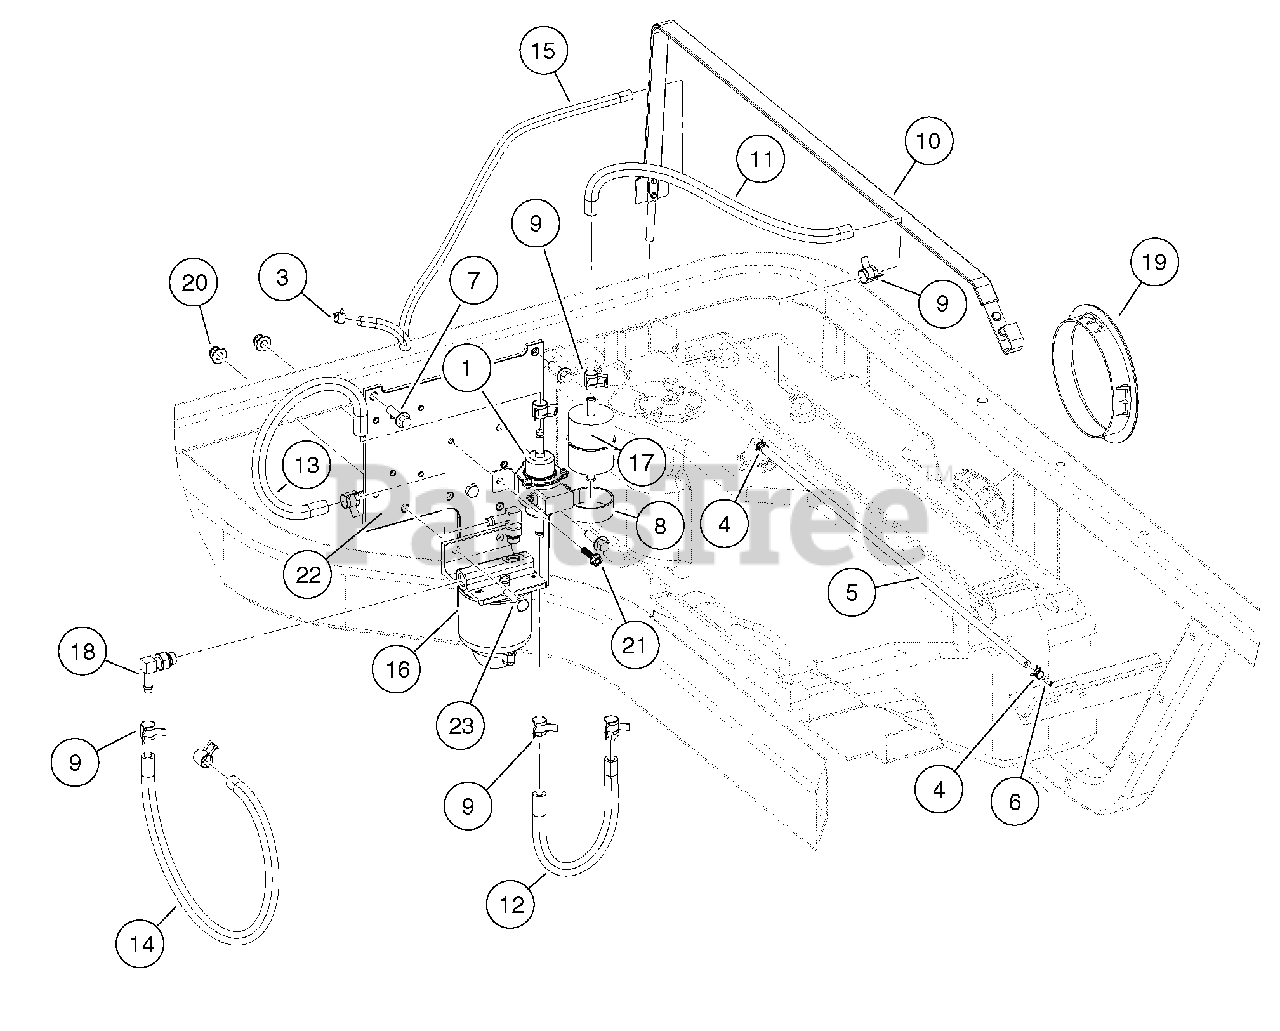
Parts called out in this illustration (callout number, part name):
1	Pump, Diesel Fuel Electric
2	Asm, Fuel System, Kubota
3	Clamp, Green Hose
4	Clamp, 0.301 ID Hose
5	Hose, Fuel, Vent, 22" Long
7	Screw, M8X1.25X30, Hex
8	P-Clamp, Insulated 1.75 In
9	Clamp, Hose, Ctb 14mm
10	Strap, Tank, Fuel
11	Hose, Tank To Prefilter Diesel
12	Hose, Fuel Prefilter To Pump
13	Hose, Fuel Pump To Filter
14	Hose, Fuel Filter To Eng
15	Hose, Fuel Return
16	Filter Assy, Fuel
17	Filter, Fuel
18	Adapter, 90, 5/16 Tube
19	Bezel, Fuel Fill
20	Lock Nut, Flg M8 X 1.25 Nylon
21	Screw, M6 X 1 X 25 Thd Form
22	Plate, Fuel/Oil System
23	Bolt, M8 X 1.25 X 30
